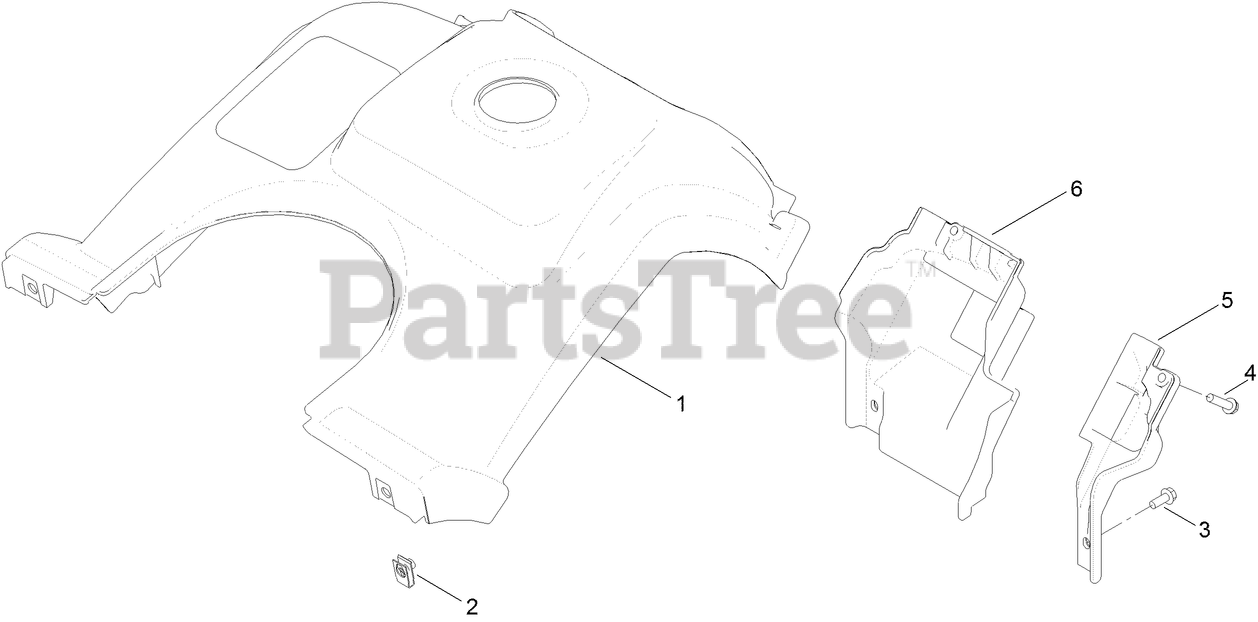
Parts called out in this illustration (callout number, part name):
1	SHROUD ASM
3	SCREW-HWH
4	SCREW-PLASTIC
5	SHROUD-LOWER, LH
6	SHROUD-LOWER, RH
